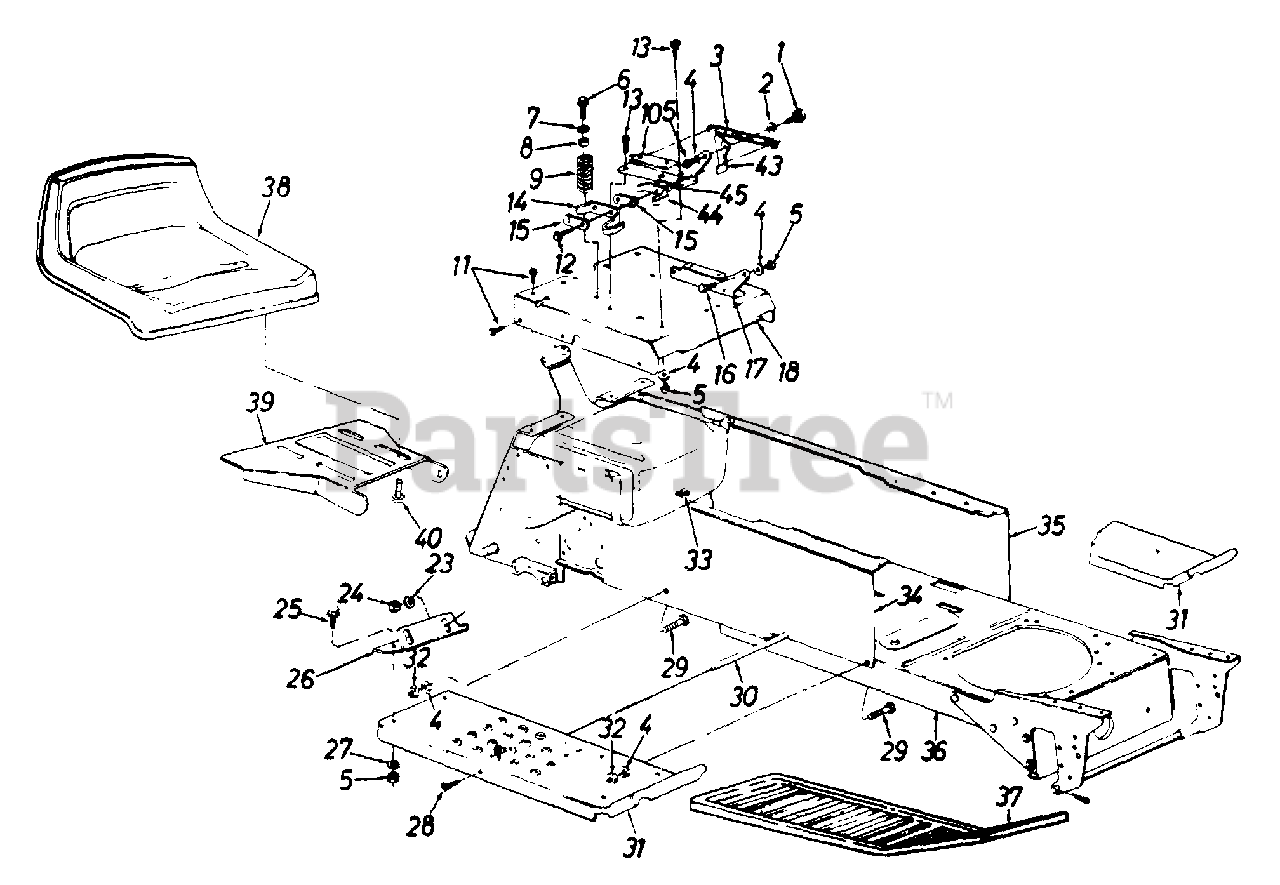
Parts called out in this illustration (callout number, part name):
1	Shld. Bolt .437" Dia. x .162"
2	Spr. Wash..445" I.D.
3	Ext. Spring 5.31" Lg.
4	L-Wash. 5/16" I.D.
5	Hex Nut 5/16-18 Thd.
6	Hex Wash. Hd. Tap Scr. 5/16-18 x .7" Lg.
7	Fl-Wash..344" I.D.
8	Bushing
9	Compression Spring
12	Hex Wash. Hd. AB-Tap Scr. #8 x .5" Lg.
13	Torx Hd. AB-Tap Scr. 5/16-18 x .75' Lg.
14	Spring Switch
15	Insulator Plate
16	Shld. Bolt .437" Dia. x .162"
24	Hex Nut 1/4-20
25	Hex Bolt 5/16-18 x 75" Lg.
28	Truss Mach. Scr. 5/16-18 x .75" Lg.
29	Rib Neck Bolt 5/16-24 x .75" Lg.
30	Running Board Rod
33	Speed Nut #102
34	R.H. Side Frame
35	L.H. Side Frame
38	Seat 10-5/8" High
39	Seat Pivot Bracket
40	Hex Tap Scr. 3/8-16 x .75" Lg.
43	Seat Lift Bracket
44	Seat Spring Switch
45	Insulator Boss Plate
